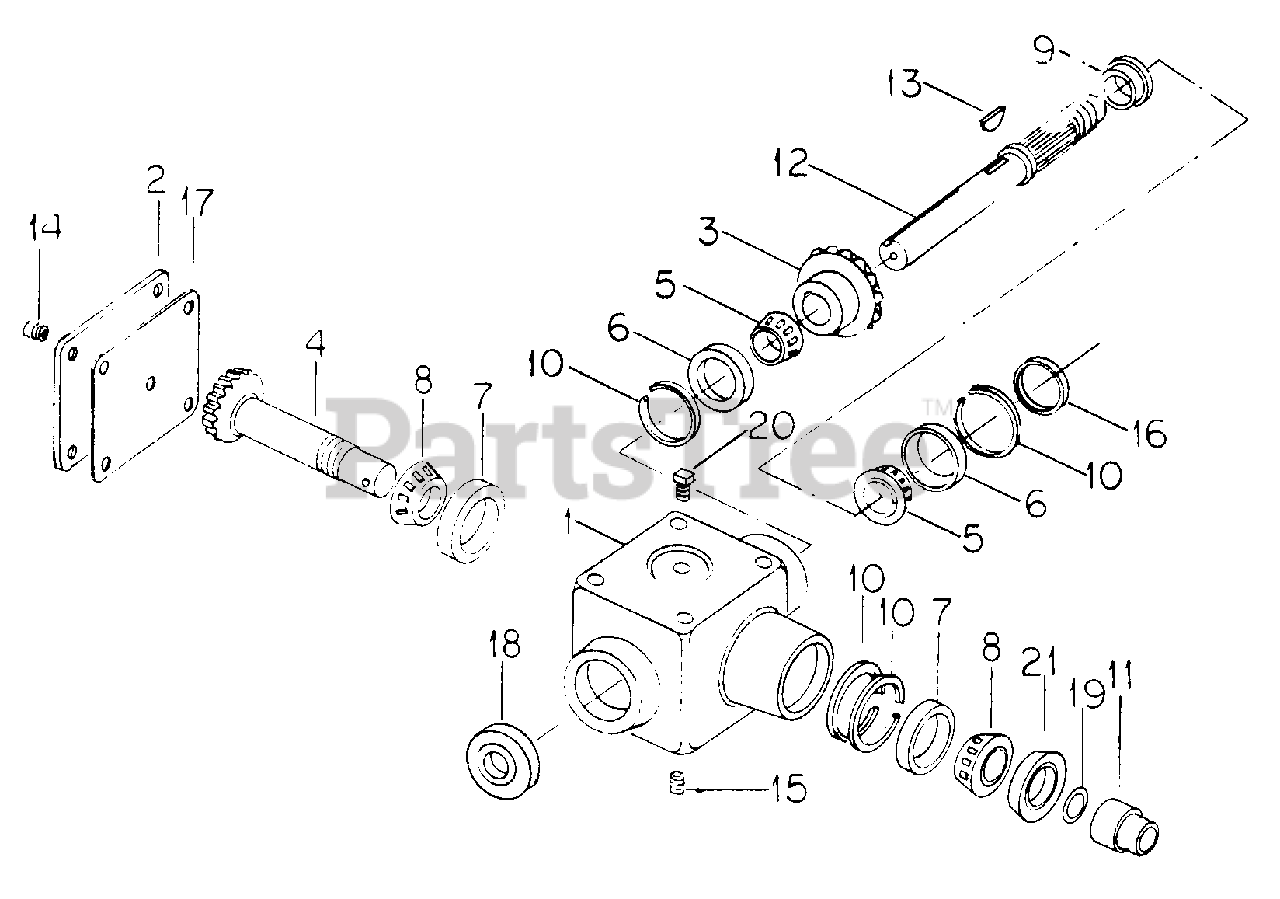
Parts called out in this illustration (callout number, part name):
1	Housing, Gear Box
4	Shaft, Bevel Pinion
5	Bearing, Cone
6	Bearing, Cup
7	Bearing, Cup
8	Bearing, Cone
12	Shaft, Output
13	Key, 1/4 X 7/8 SAE Woodruff
14	Plug, 1/8-27 Sq/Hd Auto Pipe
15	Plug, 3/8-18 Hex/Skt Auto Pipe
19	O-Ring, 1-1/8 X 1-5/16 Class 5
20	Plug, Vent
